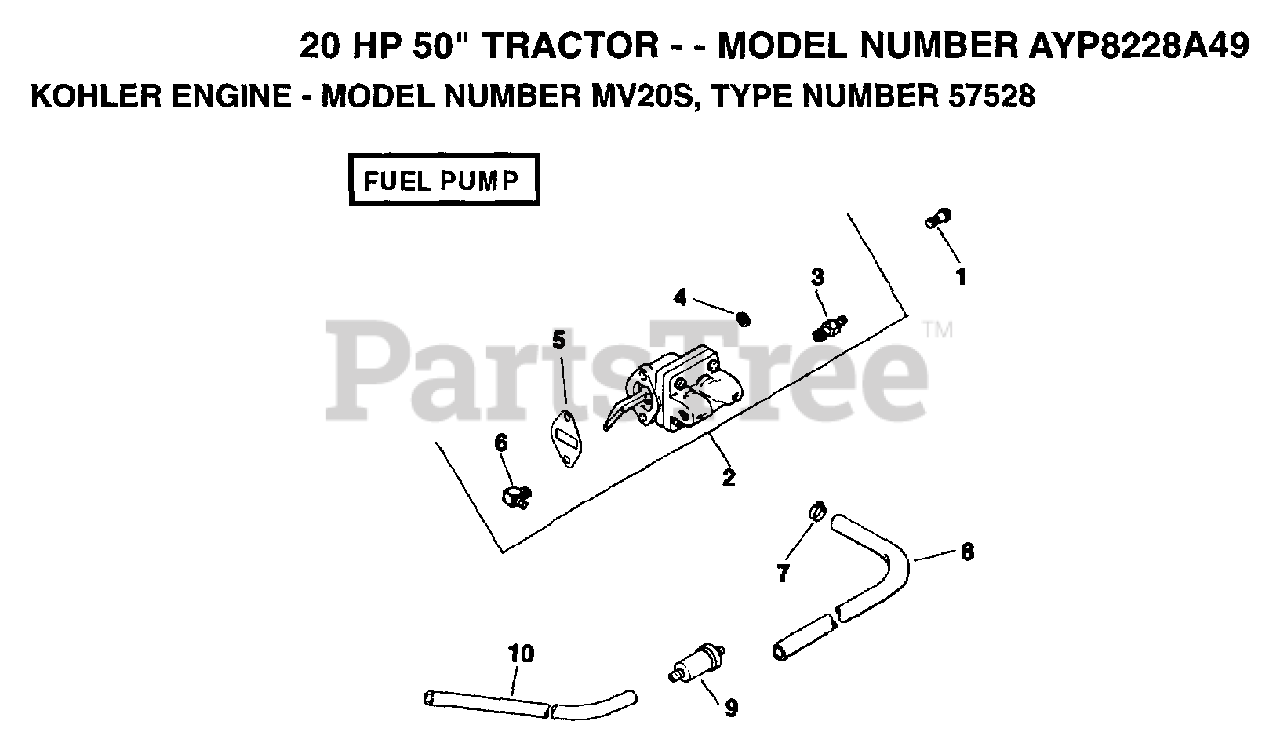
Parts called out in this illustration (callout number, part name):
3	CONNECTOR, HOSE
4	WASHER, PLAIN 1/4
7	CLAMP, HOSE
8	LINE, FUEL 8"
10	LINE FUEL 11-1/2"
